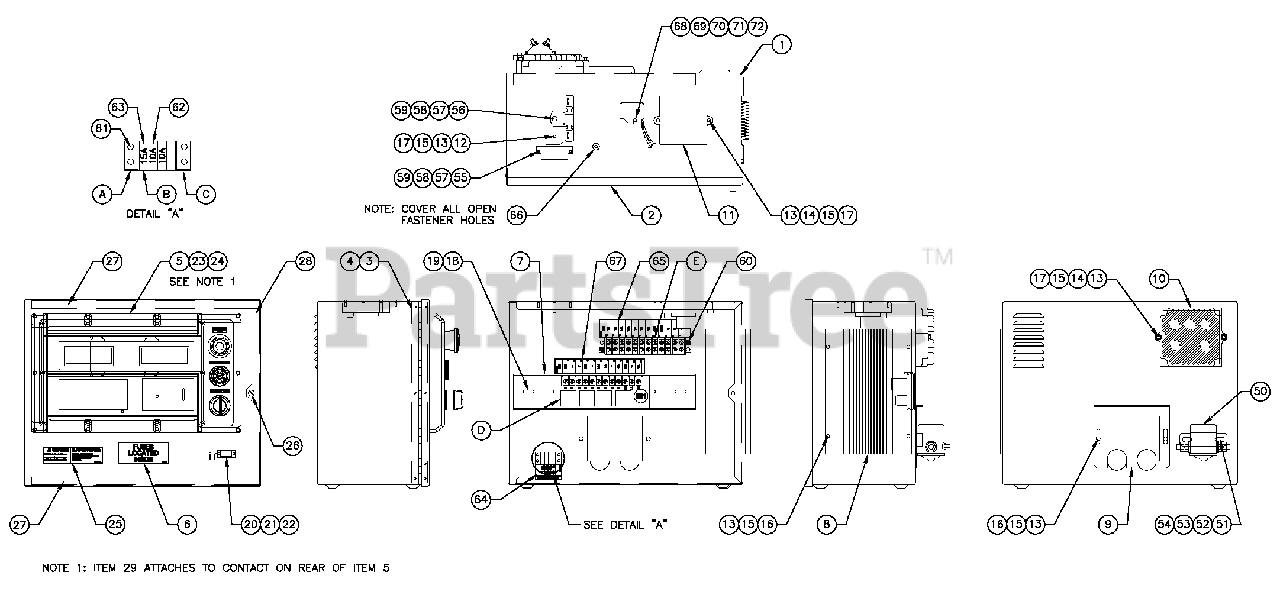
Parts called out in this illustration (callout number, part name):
1	ENCLH/G CONTROL PANEL
2	COVER CONTROL PANEL
3	HINGE CONTINUOUS H PANEL
4	RIVET POP .125X.275SS
5	ASSY PROGRAMMED H-100
6	DECAL FUSES LOCATED INSIDE
7	RAIL SNAPTRACK PCB HOLDER BULK
8	ASSY PCB 10A UL BATT CHRGR12V
9	PLATE HARNESS CLAMP
10	ASSY PCB PWR AVRW/AMP HEADER
11	ASSY PCB BOSCH GOV DRIVER
12	DIO BRIDGE 25A 600V
13	WASHER LOCK M5
14	SCREW PPHM M5-0.8X 30 SS
15	WASHER FLAT M5
16	SCREW HHPMM5-0.8X 12
17	NUT HEX M5-0.8 G8 YEL CHR
18	WASHER FLAT M4
19	SCREW PHTT M4-0.7 X 10 ZYC
20	CONN DUST CAP W/CHAIN DB9
21	WASHER FLAT M3.5
22	SCREW PHTT M3.5-0.6X 10
23	SCREW PPHM M4-0.7X 8 BLX OX
24	WASHER LOCK #8-M4
25	DECAL WRN BATT CHRG 12/24V BI
26	M5-0.8 CAPTIVE PANEL KNLD HD
27	SEAL COVER 3.18X12.7X382
28	SEAL COVER 3.18X12.7X283
29	HARNESS H-PNL INTEGRATED SW (NOTSHOWN)
50	RELAY CONTACTOR 12VDC
51	SCREW HHC 1/4-20 X 3/4 G5
52	WASHER FLAT M 6 -1/4
53	WASHER LOCK M6-1/4
54	NUT HEX 1/4-20 STEEL
55	CIRCT BRK 7 X 1 ETA 46-500-P
56	RES WW 15R 5 * 25W QK CONN
57	WASHER LOCK M3
58	NUT HEX M3-0.5 G8 YEL CHR
59	WASHER FLAT M3
60	SCREW PHTT #6-32 X 5/8 ZYC
61	SCREW PHTT #6-32 X 3/8 ZYC
62	FUSE ATO TYPE 10 AMP (RED)
63	FUSE ATO TYPE 15 AMP (BLUE)
64	DECAL CPL CONTROL PANEL FUSES
65	DECAL CPL 5.4/6.8LTB3
66	SEAL WEATHER .45" DIA
67	DECAL CPL 5.4/6.8L RELAY BOARD
68	ASSY PCB CAM TO DIST SENSOR
69	SCREW PPHM M5-0.8X 12ZNC
70	WASHER FLAT M5
71	WASHER LOCK M5
72	NUT HEX M5-0.8 G8 CLEAR ZINC
A	ADPTR RH SIDE WICKMANN 178.6191
B	HOLDER FUSE WICKMANN 178.6150
C	ADPTR LH SIDE WICKMANN 178.6192
D	ASSY PCB G-PANEL RELAY 12VDC
E	BLOCK TERM 20A12 X 6 X 1100V
